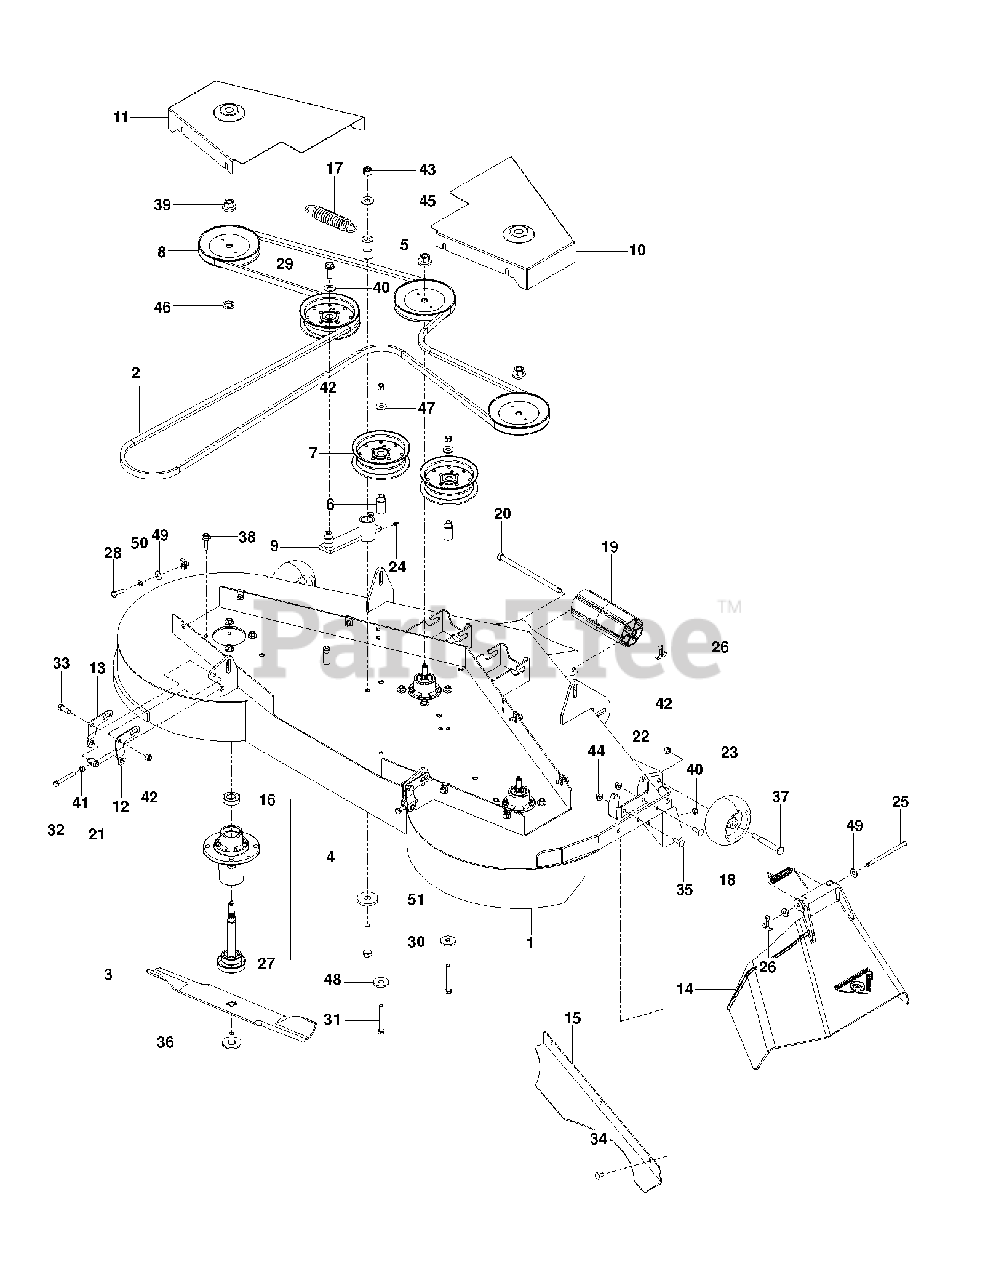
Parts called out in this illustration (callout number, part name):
3	BLADE, 21"
4	MANDREL ASM, CAST IRON
5	PIVOT BUSHING
6	IDLER BUSHING
7	PULLEY, IDLER
9	IDLER ARM
10	SHIELD, BELT 61 BLUE RH
11	SHIELD, BELT 61 BLUE LH
12	PITCH, ADJUST, RT
13	PITCH, ADJUST, LT
14	DISCHARGE CHUTE 61"
15	CONFINEMENT PLATE 61
16	BEARING, BALL
18	SPRING - TORSION
19	NOSE ROLLER 48"
20	ROD.ROLLER.NOSE.NARROW.48"
21	TRUNION, PITCH
24	ZERK
25	PIN-CLEVIS 5/16 DIA X 5.19 ZD
26	COTTER PIN 1/8 X 3/4
27	SHAFT ASM MANDREL
28	HCS 5/16C X 3/4
29	HCS 3/8C X 1 SERRATED HEAD
30	HCS 1/2C X 3 1/4
31	HCS 3/8C X 3
32	HCS 5/16-18 X 2 1/2 TPBLT
33	HCS 3/8C X 1
34	CARRIAGE BOLT 5/16C X 5/8"
35	RHSSNB 5/16C X 1.0
36	BOLT.WASHER.ASM.7/16-2
37	SHOULDER BOLT 1/2X2-5/8 ZD SPE
40	NUT 5/16 NYLOC
41	NUT 5/16C HEX
42	NUT 3/8-16 NYLOC
43	NUT 1/2-13 HEX NYLOC ZD
44	5/16-18 NYLOC FLANGE NUT
45	WASHER 1/2 FLAT
47	WASHER 3/8 FLAT
48	SPINDLE WASHER
49	WASHER 5/16 FLAT
50	WASH 5/16 DISC SPRING ZD
51	WASHER, SUPPORT
